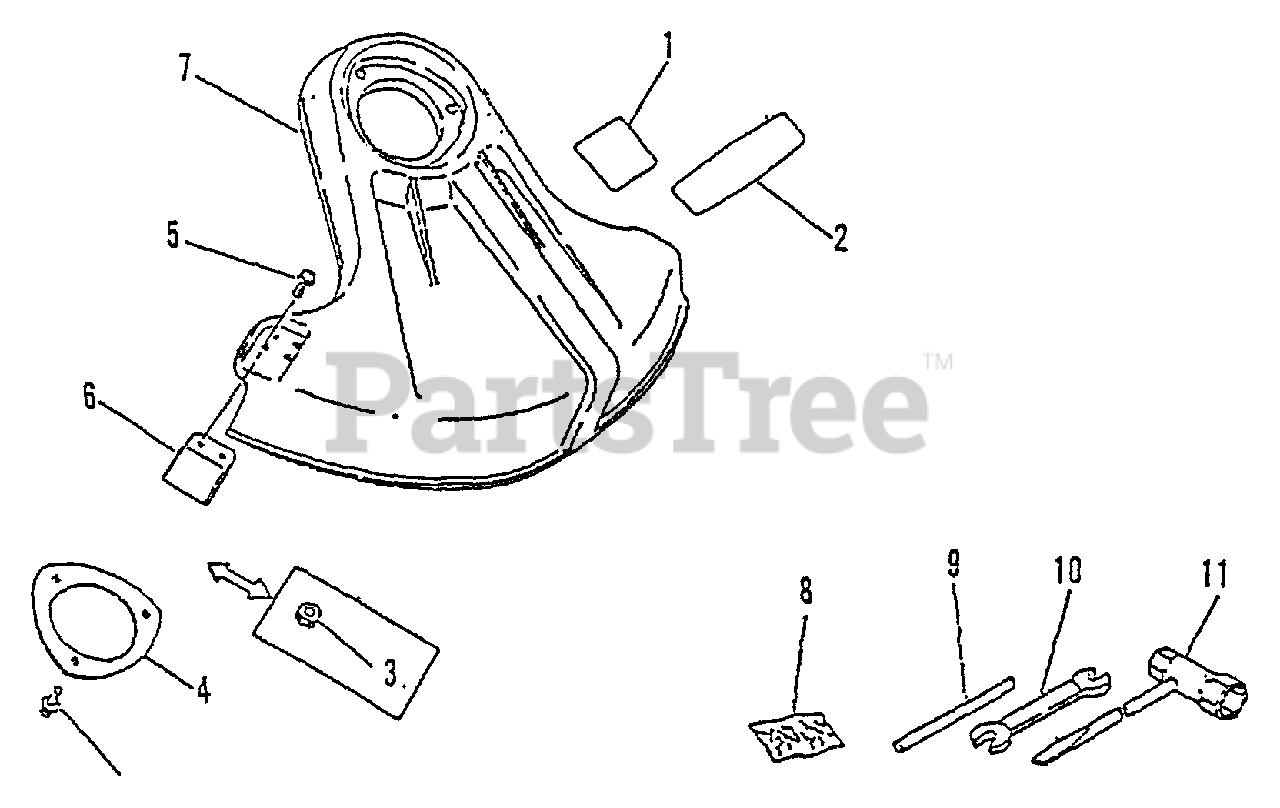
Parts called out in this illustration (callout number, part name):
1	LABEL - CAUTION
2	LABEL - ECHO
4	PLATE, SHIELD
5	SCREW - 5X16
6	KNIFE, TRIMMER LINE
7	DEBRIS SHIELD KIT
8	PIN, SPLIT - 2X22
9	LOCKING TOOL
10	SPANNER - 8X10mm
11	T-WRENCH - 17X19mm
